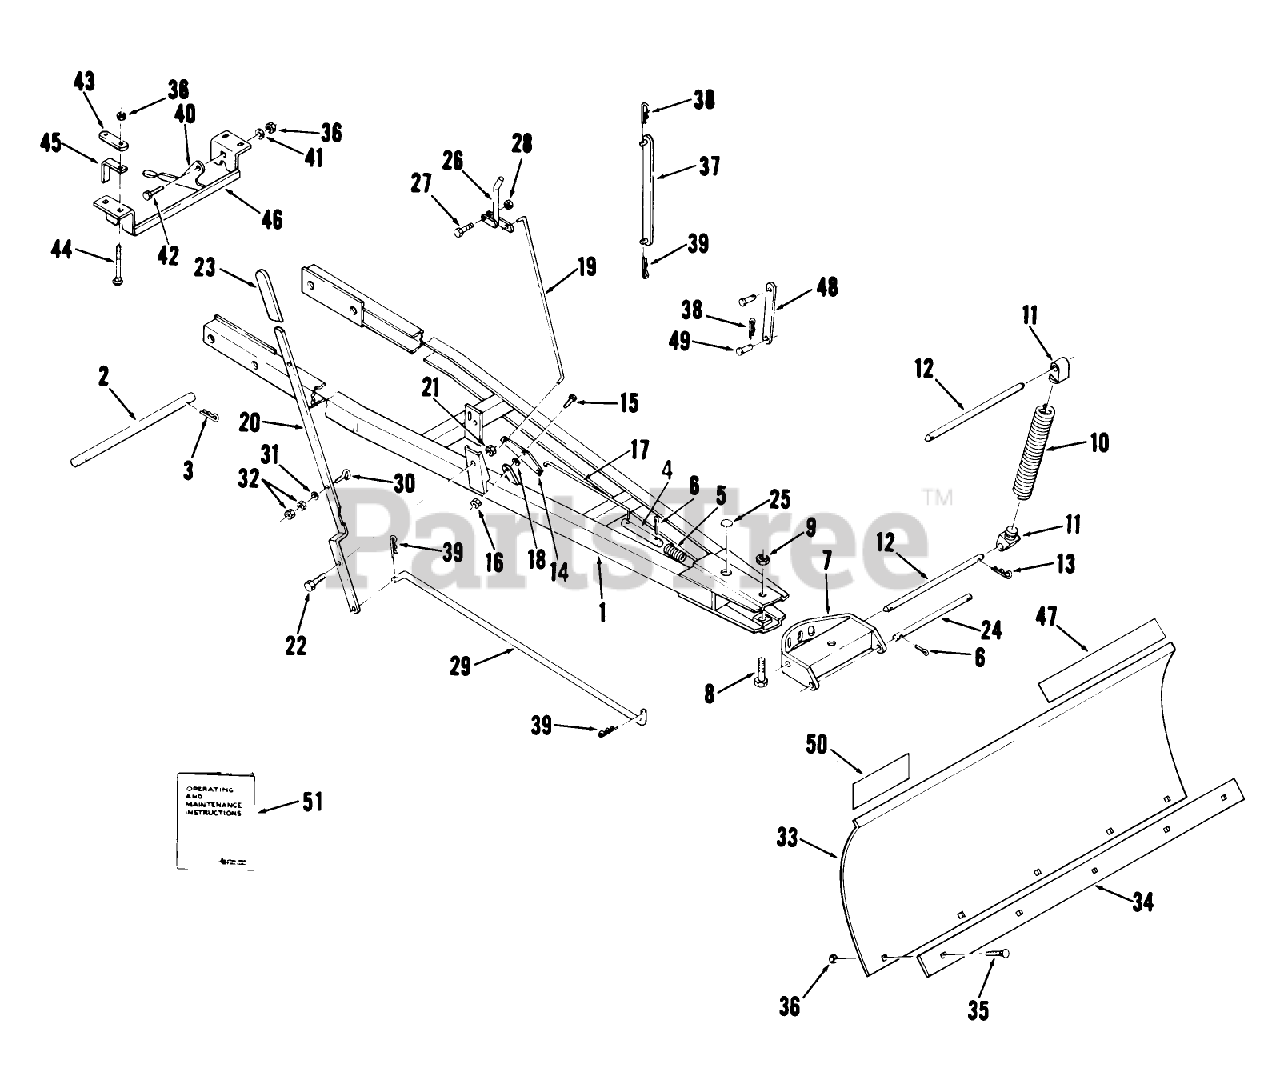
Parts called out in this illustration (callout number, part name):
3	Hairpin
5	SPRING-COMPRESSION
12	ROD-PIVOT, BLADE
13	Hairpin
17	LOWER INDEX ROD
23	GRIP
24	ROD-LOWER
25	PLUG
33	ORD 109593 & 109596
38	Hairpin Cotter
39	Hairpin
40	PLATE-LATCHING
43	BRACKET-REAR LINK MOUNTING
45	SPACER-BRACKET
48	LINK-LIFT
51	Operating and Maintenance Instructions
